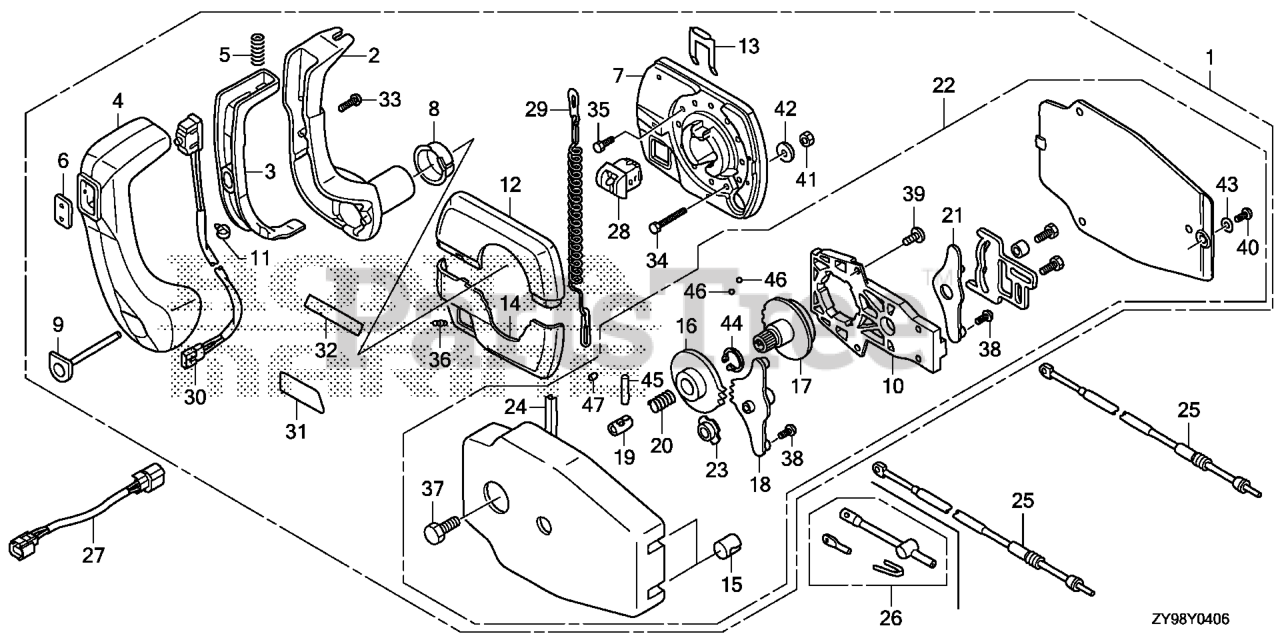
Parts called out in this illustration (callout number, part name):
1	BOX ASSY., REMOTE CONTROL (PANEL MOUNT) (NA USE ALT:06240-ZW7-U00)
2	HANDLE, REMOTE CONTROL
3	LEVER, HANDLE LOCK
4	GRIP, REMOTE CONTROL HANDLE
5	SPRING, REMOTE CONTROL HANDLE
6	COVER, GRIP
7	HOUSING ASSY., REMOTE CONTROL BOX (A)
8	BUSHING Use up to Frame SN 4000953.
9	BUTTON, THROTTLE
10	FRAME ASSY., REMOTE CONTROL BOX
11	BAND B, CABLE Use up to Frame SN 4000953.
12	HOUSING ASSY., REMOTE CONTROL BOX (B)
13	RETAINER
14	HOUSING, REMOTE CONTROL BOX (C)
15	GROMMET
16	WHEEL, CONTROL
17	SHAFT, HANDLE (N/A: SEE ASSEMBLY) (NOT AVAILABLE)
18	ARM ASSY., SHIFT LINK
19	SHAFT, GEARSHIFT
20	SPRING, GEARSHIFT
21	ARM ASSY., THROTTLE LINK
22	HOUSING ASSY. (INNER) (PANEL MOUNT)
23	BUSH
24	SPRING
25	CABLE, REMOTE CONTROL (10') (TELEFLEX)
25	CABLE, REMOTE CONTROL (10') (NOT AVAILABLE)
25	CABLE, REMOTE CONTROL (11') (TELEFLEX)
25	CABLE, REMOTE CONTROL (1 1'') (BRUNSWICK) (NOT AVAILABLE)
25	CABLE, REMOTE CONTROL (12') (TELEFLEX)
25	CABLE, REMOTE CONTROL (1 2'') (BRUNSWICK) (NOT AVAILABLE)
25	CABLE, REMOTE CONTROL (13') (TELEFLEX)
25	CABLE, REMOTE CONTROL (1 3'') (BRUNSWICK) (NOT AVAILABLE)
25	CABLE, REMOTE CONTROL (14') (TELEFLEX)
25	CABLE, REMOTE CONTROL (1 4'') (BRUNSWICK) (NOT AVAILABLE)
25	CABLE, REMOTE CONTROL (15') (TELEFLEX)
25	CABLE, REMOTE CONTROL (1 5'') (BRUNSWICK) (NOT AVAILABLE)
25	CABLE, REMOTE CONTROL (16') (TELEFLEX)
25	CABLE, REMOTE CONTROL (1 6'') (BRUNSWICK) (NOT AVAILABLE)
25	CABLE, REMOTE CONTROL (17') (TELEFLEX)
25	CABLE, REMOTE CONTROL (1 7'') (BRUNSWICK) (NOT AVAILABLE)
25	CABLE, REMOTE CONTROL (18') (TELEFLEX)
25	CABLE, REMOTE CONTROL (1 8'') (BRUNSWICK) (NOT AVAILABLE)
25	CABLE, REMOTE CONTROL (19') (TELEFLEX)
25	CABLE, REMOTE CONTROL (1 9'') (BRUNSWICK) (NOT AVAILABLE)
25	CABLE, REMOTE CONTROL (20') (TELEFLEX)
25	CABLE, REMOTE CONTROL (2 0') (BRUNSWICK) (NOT AVAILABLE) (ALT. PNO: 24920-ZW1-003AH)
26	ADAPTER, REMOCON CABLE (N/A: USE 24931-ZW1-000)
27	HARNESS ASSY., POWER TRIM-TILT Use from Frame SN 4000954.
28	SWITCH ASSY., EMERGENCY STOP
29	WIRE, EMERGENCY
30	SWITCH ASSY., POWER TRIM-TILT (A) Use up to Frame SN 4000953.
31	MARK, REMOTE CONTROL (A)(PANEL)
32	MARK, REMOTE CONTROL (B)(FOR STARBOARD)
32	MARK, REMOTE CONTROL (C)(FOR PORT)
33	SCREW A (NOT AVAILABLE)
34	SCREW B
35	SCREW C
36	SCREW SET (1/4-20X16") Use up to Frame SN 4000953.
37	BOLT
38	SCREW (8-32X3/8)
39	SCREW (10-32X5/8)
40	SCREW (10-32X5/8)
41	NUT (1/4X20)
42	WASHER
43	WASHER Use up to Frame SN 4000953.
44	CIRCLIP (OUTER)
45	PIN, GEARSHIFT
46	BALL, STEEL
47	ROLLER, SHIFT CLICK
